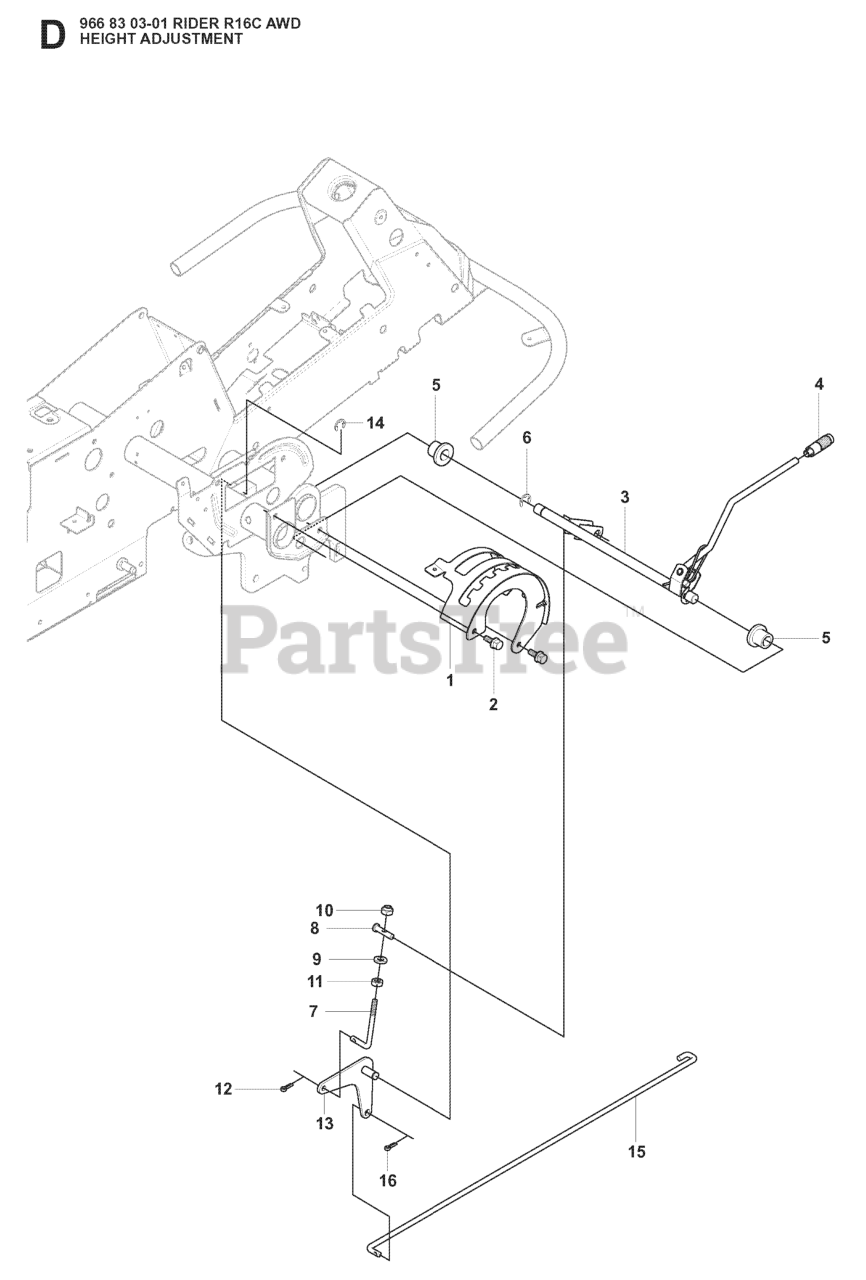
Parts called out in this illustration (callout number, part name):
1	CONTROL PLATE
3	HEIGHT ADJUSTER
4	GEAR STICK KNOB
5	BUSHING
9	WASHER
10	LOCKNUT M8
11	NUT
13	LINK HEIGHT ADJUSTMENT
14	RETAINING RING
15	CONNECTION ROD
